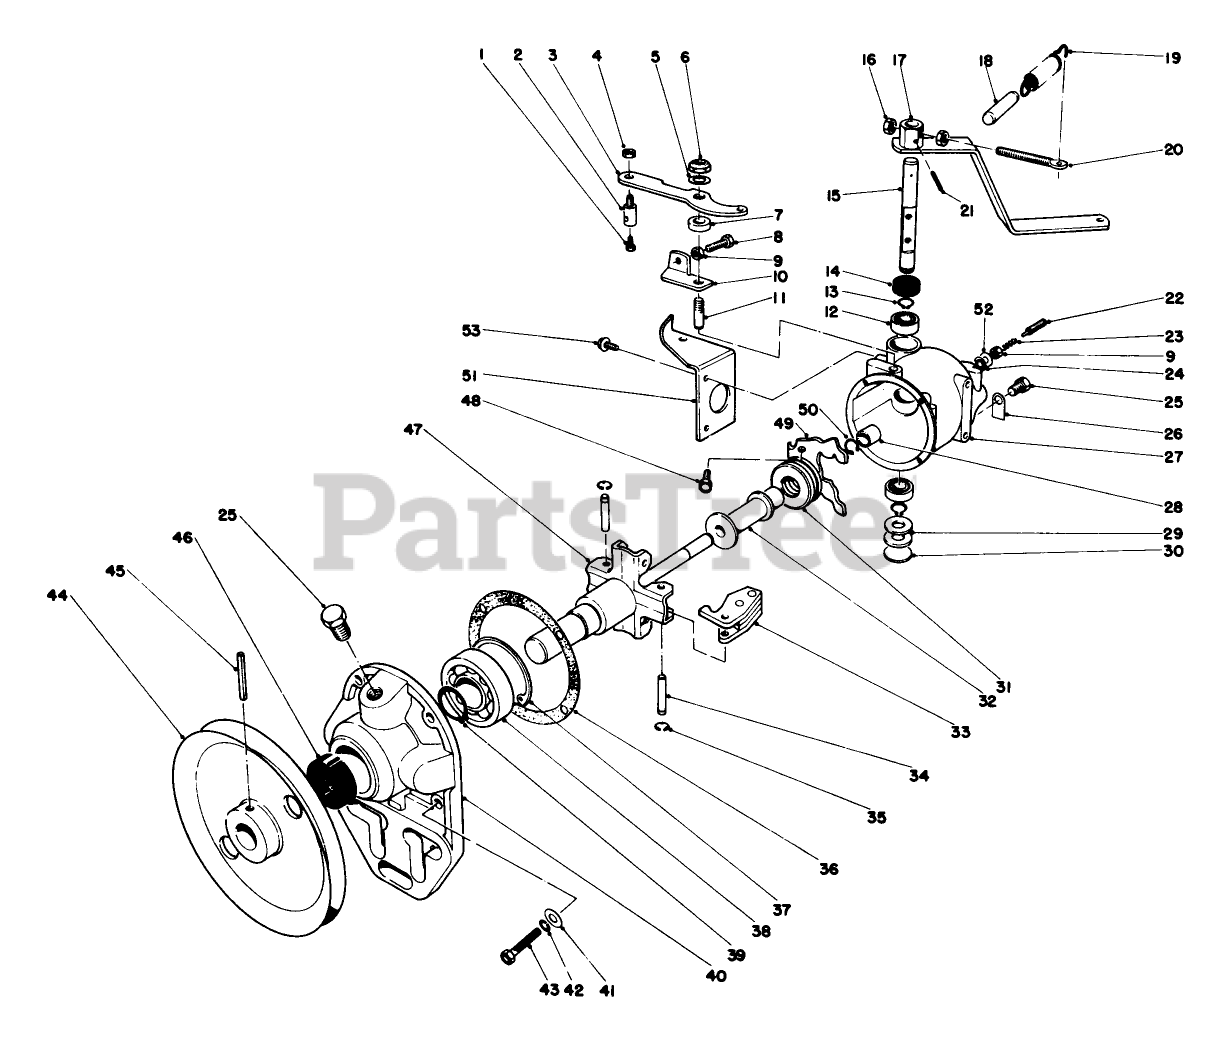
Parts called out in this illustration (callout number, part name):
1	SCREW-HH
2	SWIVEL
3	Speed Change Lever
4	NUT-LOCK, NI
5	WASHER
6	STOP NUT
7	Spacer
8	SCREW-HH
9	NUT-HEX
10	Stop Bracket
12	BALL BRG
13	EXT SNAP RING
14	OIL SEAL
15	Rocker Shaft
16	NUT-HEX
17	THROTTLE LEVER ASM
18	FORCED IDLE PLUG
19	SPRING
20	EYESCREW
21	PIN-ROLL
22	BUMPER SCREW
23	BUMPER SPRING
24	SEALING WASHER
25	PIPE PLUG
26	OIL LEVEL TAG
28	DRIVE SHAFT BUSHING
29	WASHER
30	WELCH PLUG
31	Thrust Bearing
32	Thrust Sleeve
33	WEIGHT ASM
34	Weight Pin
35	E RETAINING RING
36	GASKET
37	INT BEVELED
38	BEARING-BALL
39	RETAINING RING
40	FLANGE
41	WASHER-FLAT
42	WASHER-LOCK
43	10-24 X 7/8 IND HD SC
44	Pulley
45	PIN-SPRING
46	OIL SEAL
47	SPIDER & SHAFT ASM
48	MACHINE SCREW
50	RETAINING RING
51	Bracket
52	Shim Washer
53	SCREW
